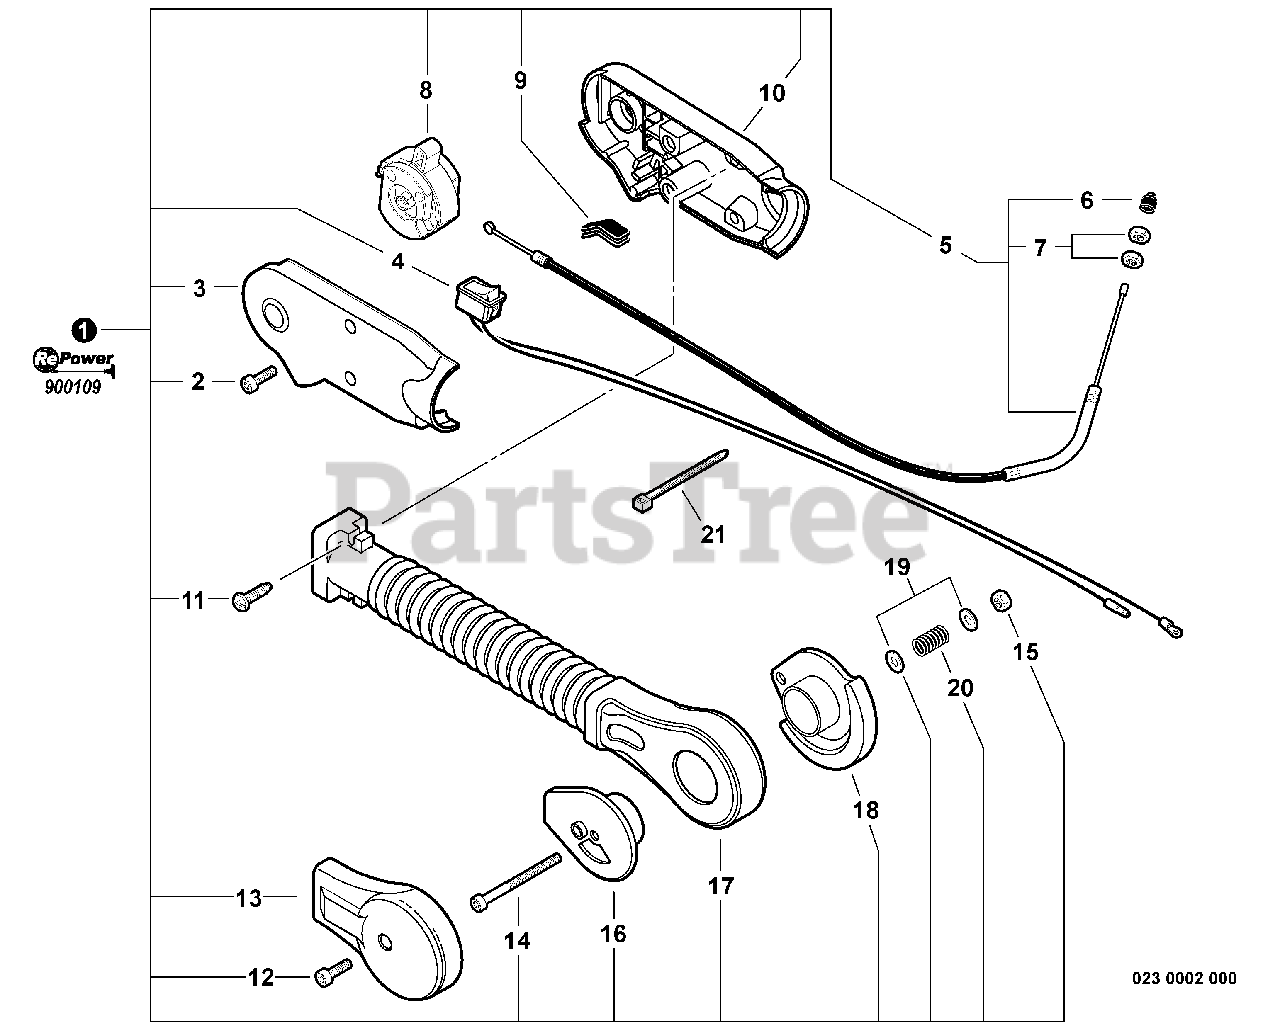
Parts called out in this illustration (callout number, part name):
1	HIP MOUNT THROTTLE CONTROL KIT
2	SCREW - 5X14
3	HANDLE, CONTROL - LEFT
4	SWITCH, IGNITION
5	THROTTLE CABLE ASSY
6	CAP, DUST
8	CONTROL, THROTTLE
10	HANDLE, CONTROL - RIGHT
11	SCREW - 5X20
12	SCREW - 5X14
13	COVER, ARM
14	SCREW - 5X80
15	LOCKNUT - 5
16	FIXTURE, TRIGGER BRACKET - LEFT
17	ARM, THROTTLE CONTROL
18	FIXTURE, TRIGGER BRACKET - RIGHT
21	TIE, CABLE - SMALL
